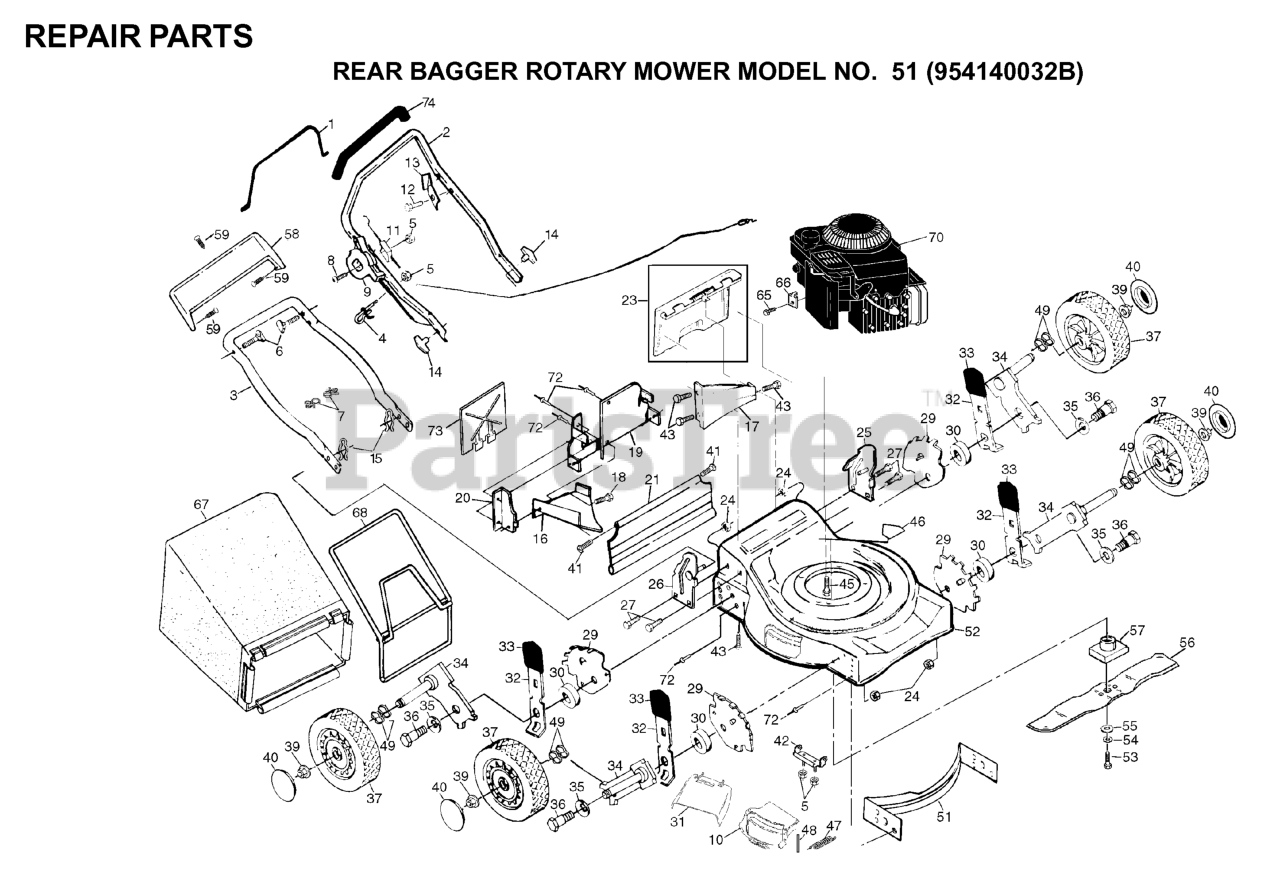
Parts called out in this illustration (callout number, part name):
1	CONTROL BAR/BLACK
2	UPPER HANDLE
3	HANDLE, LOWER
4	ROPE GUIDE
5	NUT
6	HANDLE BOLT
7	CLIP CABLE SNAP
8	SCREW 1/4-20 X 2.12
9	THROTTLE CONTROL
11	CABLE.MZR.51.RT.SP./PU.
12	TAPPING SCREW
13	BRACKET UPSTOP
14	HANDLE KNOB
15	HAIRPIN COTTER
16	DISCHARGE BAFFLE
17	REAR BAFFLE
18	SCREW.HXTAP.10-24
19	BACK PLATE
20	SIDE BAFFLE
21	REAR SKIRT
23	REAR DOOR ASSEMBLY KIT
24	LOCKNUT PM
25	HANDLE BRACKET ASSEMBLY - LEFT
26	HANDLE BRACKET ASSEMBLY-RIGHT
27	SELF-TAPPING SCREW 5/16-18X3/4
29	WHEEL ADJUST BRACKET
30	RP SPACER HT ADJ
32	SELECTOR SPRING
33	SELECTOR KNOB
34	AXLE, REAR
35	WASHER.BELLEVILLE (3 2 LB)
36	BOLT
37	WHEEL.8X2.PR.LP.RAD.GREY
39	HEX FLANGE LOCKNT
40	HUBCAP.8".GREY
41	HINGE SCREW
42	BRACKET.HINGE ASM.W/FIN
45	BOLT 3/8-16X1-1/8
46	DECAL HYT
47	SPRING HINGE
48	ROD.HINGE.COMBI-C
49	WAVE WASHER
51	FRONT BAFFLE
53	SCREW, HEX HD 3/8-24 X 1-3/8
54	LOCKWASHER
55	WASHER,HARDEN
56	BLADE.20.MULCH.(50DK,6020MD)
57	BLADE ADAPTOR
58	TRIM PLATE
65	SCREW.HEX.HEAD.WASHER.10-16
67	GRASS BAG
68	CATCHER.FRAME.WALK
72	RIVET BLIND
